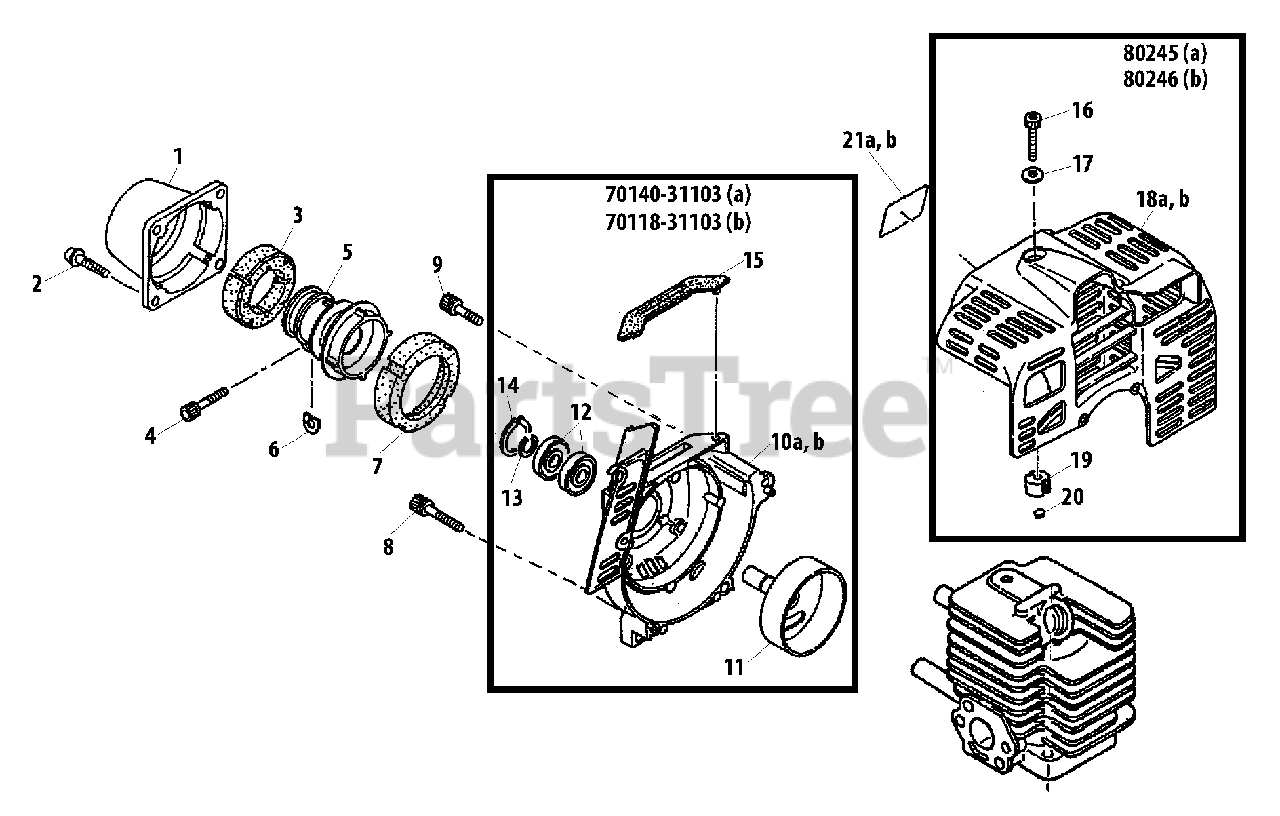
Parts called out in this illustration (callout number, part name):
1	COVER, AV CUSHION (RED)
2	BOLT M5×16
3	CUSHION, FRONT
4	BOLT M5×25
5	JOINT
6	D-WASHER
7	HOLDER, REAR CUSHION
8	BOLT M5×35
9	BOLT M5×16
10A	COVER, FAN
10B	CASE, FAN
11	DRUM, CLUTCH
12	BEARING, BALL 6000ZZ
13	RING, SNAP WR10
14	RING, SNAP Ø26
15	CUSHION
16	BOLT 5×25
17	WASHER 5 MM
18A	COVER, ENGINE
18B	COVER, ENGINE - BLUE
19	INSULATOR 5 MM
20	CLIP
21A	LABEL - MODEL
21B	LABEL - MODEL
70118-31103B	FAN CASE ASSY
70140-31103A	COVER ASSY, FAN
80245A	ENGINE COVER KIT - RED
80246B	ENGINE COVER KIT - BLUE
